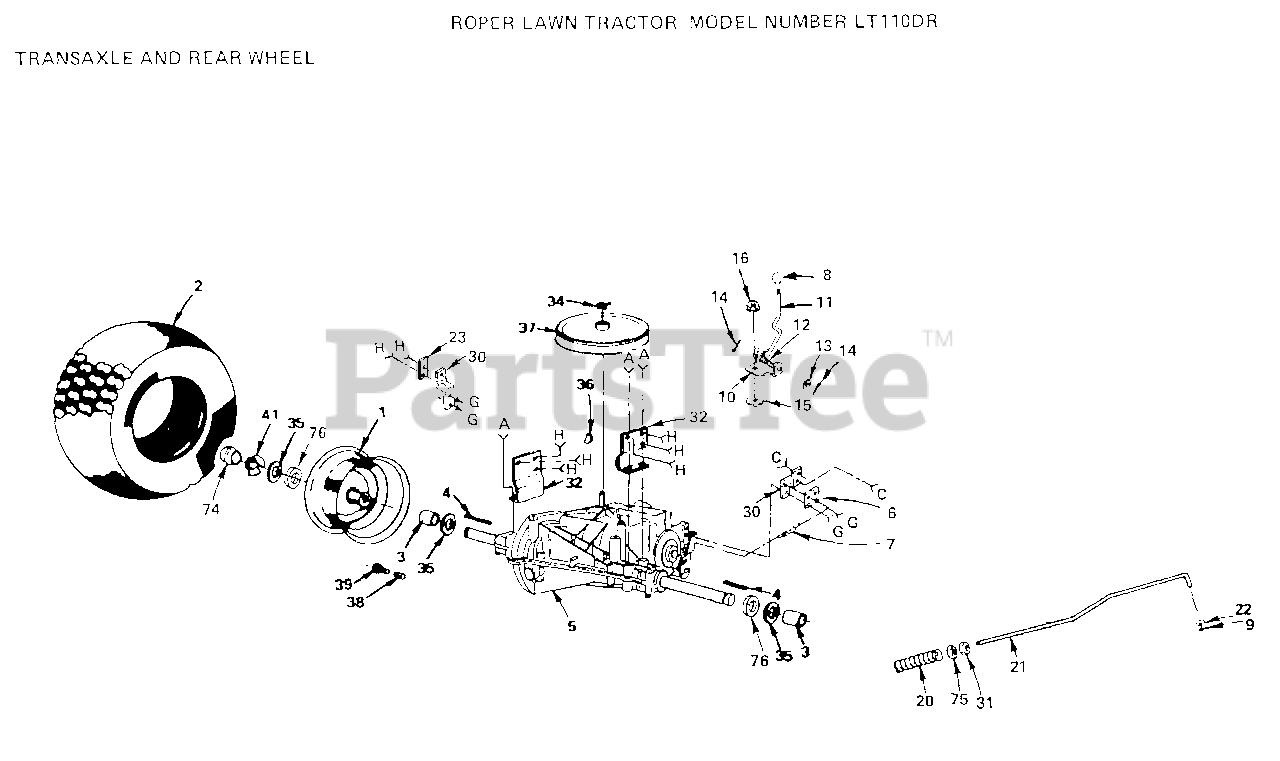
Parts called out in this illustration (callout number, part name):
3	"SPACER, SPLIT LT"
6	BRACKET-SPRING LT
7	SPRING-EXT LT
8	KNOB T (1/2-HOLE)
9	COTTER PIN
10	PLATE SHIFT LT
12	SPRING LT
13	WASHER
14	PIN COTTER 1/8
15	WASH-SHFT PLT LT
20	SPRING ROD LT
22	WASHER
23	PLATE-STRAP LT
30	"STRAP, TORQUE LT"
31	NUT
38	VALVE CAP
39	VALVE STEM LT
41	E-RING LT
74	HUB CAP
75	LOCKNUT
